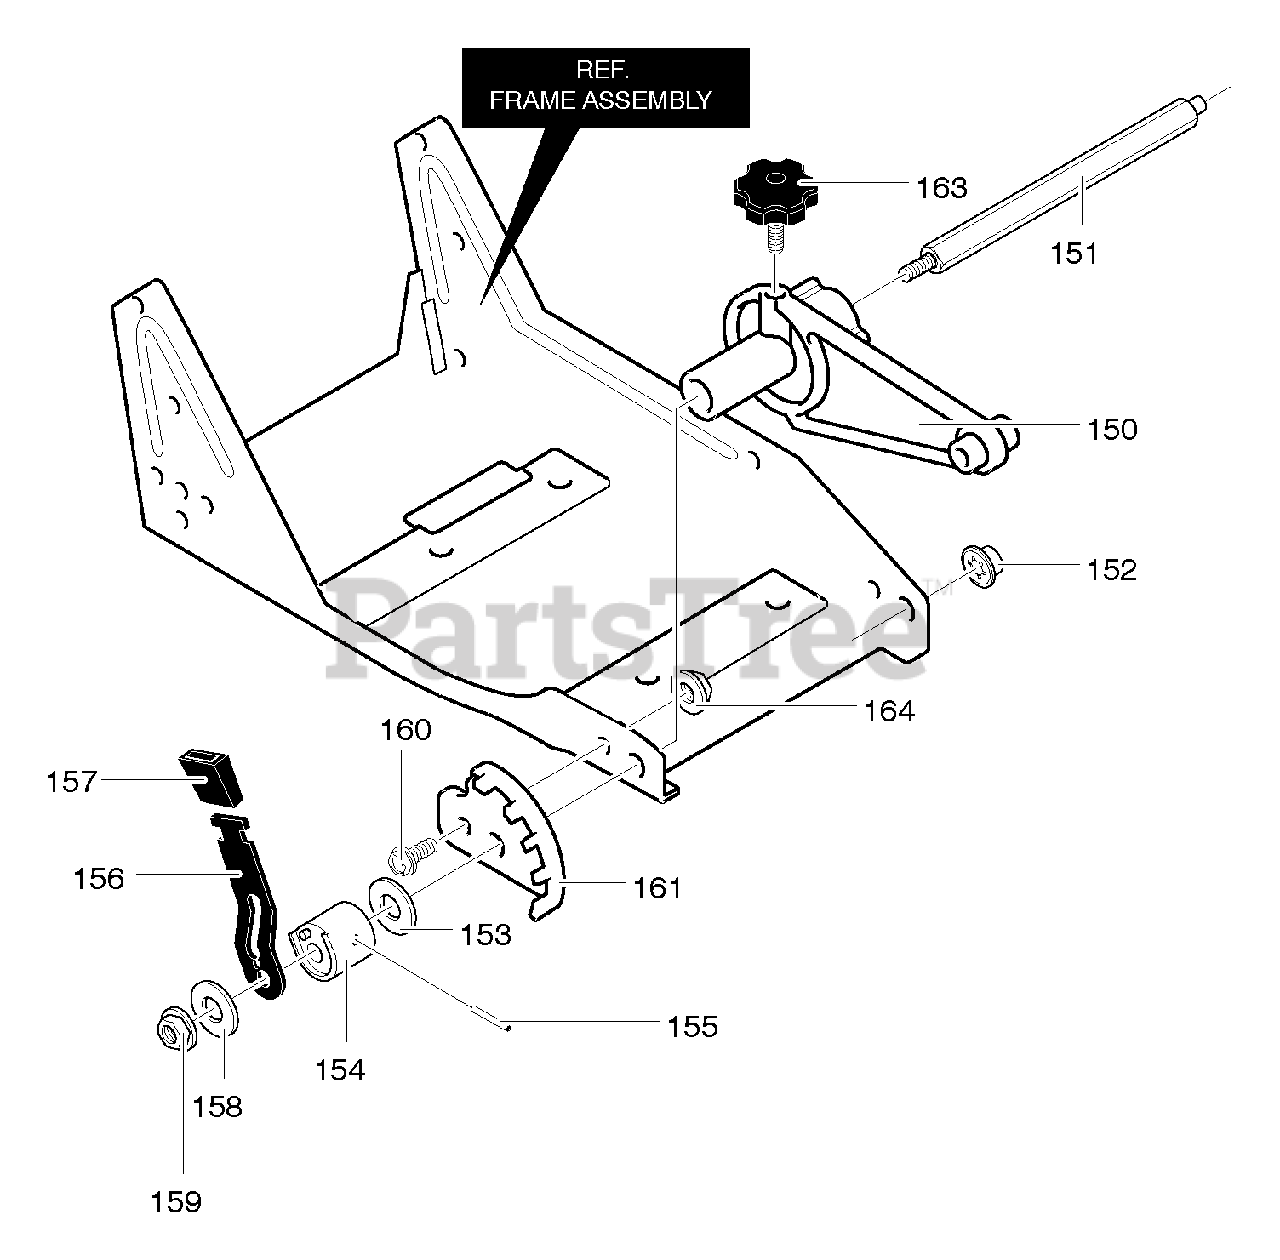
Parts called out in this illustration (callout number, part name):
150	Front Wheel Arm
151	Front Curb Hopper
152	Pushnut, Washer
153	Plastic Washer
154	Spacer, Height Adjust
155	Pin, Spring
156	Lever, Height Adjust
157	Knob, Rectangle
158	Flatwasher
160	Screw, 5/16-18 x 0.63
161	Plate, Height Adjust
163	Knob, Molded
164	Nut, 5/16-18
